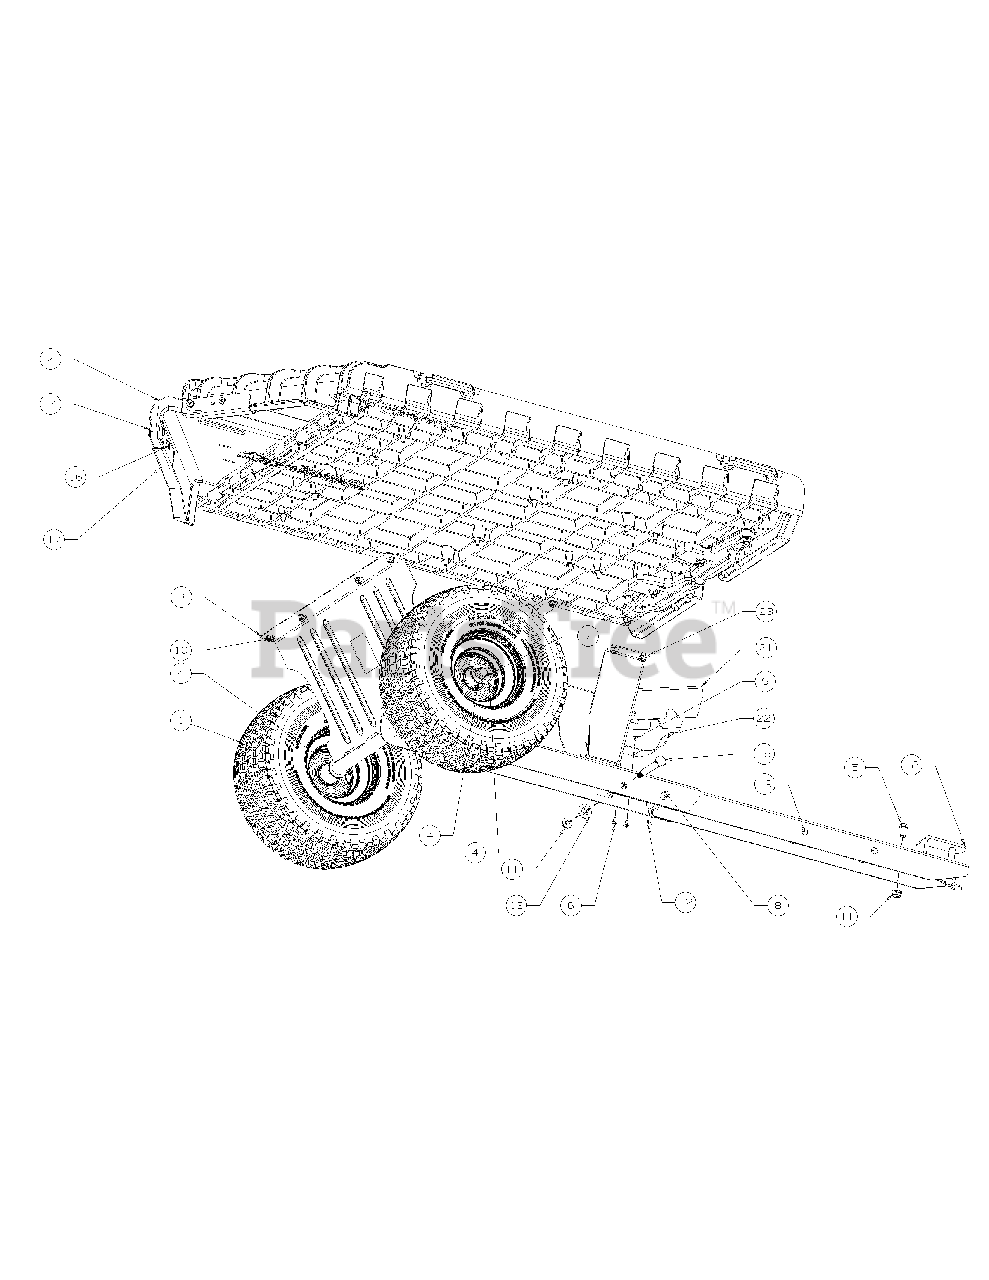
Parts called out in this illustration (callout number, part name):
1	Wheel Asm 15 X 6 X 6
2	Bed Asm:
4	Hdwr Asm:Hauler
5	Screw-Hex 3/8-16 X
6	Screw-10 X .393
7	Axle Shaft-.75 X 29.1
8	Clevis Pin: 0.5 X 3.25
9	Nut-Hex Ins L-#10-
10	Nut-Flglk 5/16-18
11	Nut-Flange Lk.Nylo
12	Pin-Internal Cotte
13	Spacer-Shld
14	Nut-Shoulder .375
15	Shoulder Screw 3/8-16
16	Shoulder Screw: 1/4-20
22	Bracket-Release
